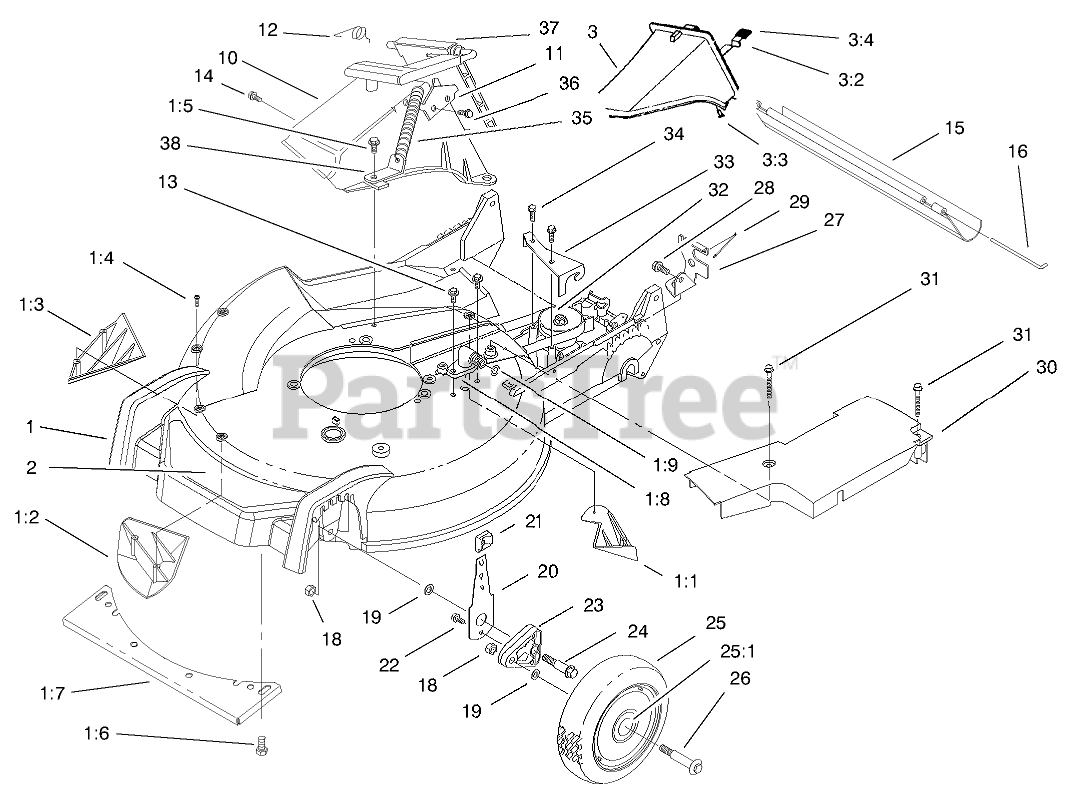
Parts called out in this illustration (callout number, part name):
1	HOUSING ASM
1:1	KICKER-REAR
1:2	KICKER-FRONT
1:3	KICKER-RH
1:4	SCREW-PPH
1:5	SCREW-HWH
1:6	SCREW-HWHTF
1:7	Shield-front
1:8	FITTING-WASHOUT
1:9	O-RING
2	DECAL - DECK
3	DISCHARGE PLUG ASM
3:2	LATCH-PLUG, DISCHARGE
3:3	RIVET-HEAD, FLAT
3:4	GRIP-LATCH
10	TUNNEL-DISCHARGE
11	LATCH-PLATE
12	RETAINER-DOOR
14	SCREW AND WASHER ASM
15	SHIELD-TRAILING
16	ROD-SHIELD
18	NUT-LOCK
19	WASHER
20	FRONT SPRING ARM ASM
21	KNOB-ARM
22	SCREW-HWH
23	ARM-PIVOT, FRONT
24	BOLT-SHOULDER
25	Wheel-ASM
25:1	BUSHING
26	BOLT-WHEEL
27	Bracket-Adj. Trac
28	SCREW-HWHTF
29	RETAINER-CABLE
30	COVER-BELT
31	SCREW-HHFTF
32	GEARCASE ASM
33	Bracket-Guide
34	SCREW-HWHTF
35	SPRING-DOOR
36	SCREW-PLASTITE
37	DISCHARGE DOOR ASM
38	BRACKET-SPRING
